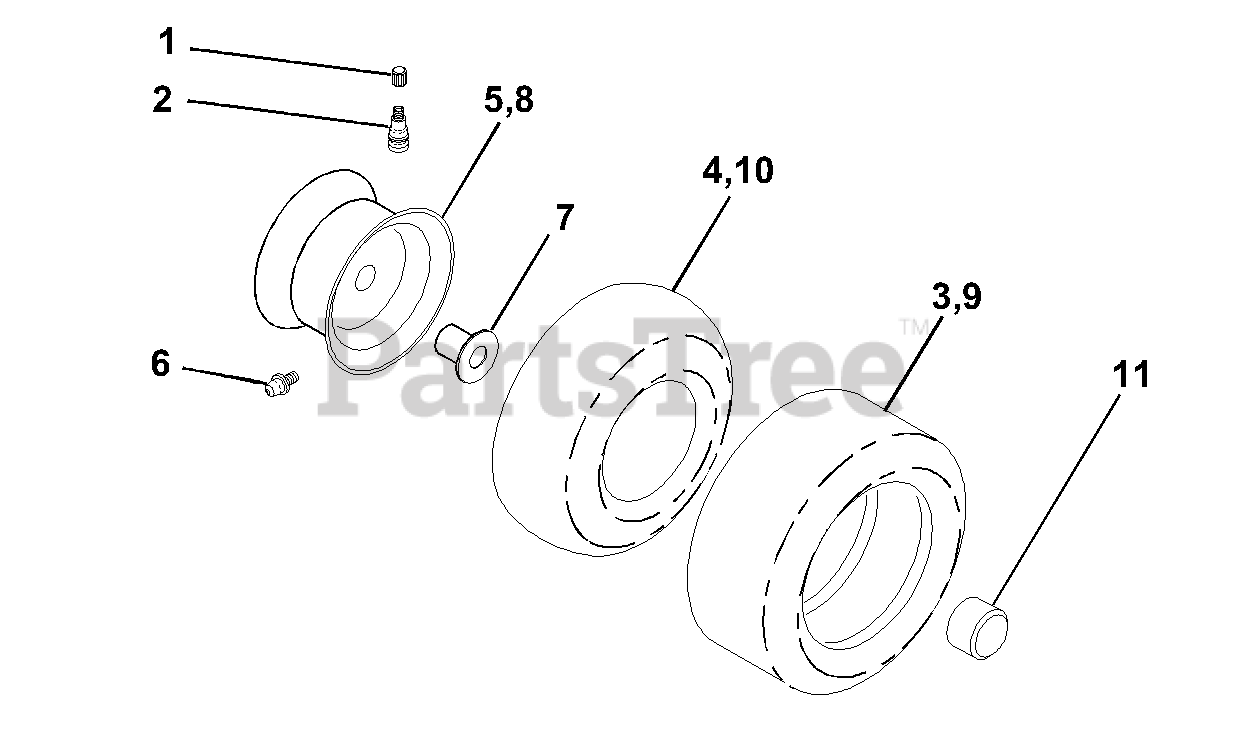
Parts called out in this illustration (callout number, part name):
1	Cap Valve Tire
2	Stem Valve
3	Tire F Ts 15 X 6 0 - 6 Service
4	Tube Front
5	Rim Asm 6"front Service
6	Fitting Grease
7	Bearing Flange
8	Rim Asm 8"rear Service
9	Tire R Ts 20x10-8 C Service
10	Tube Rear
11	Cap Axle Blk 1 50 X 1 00
